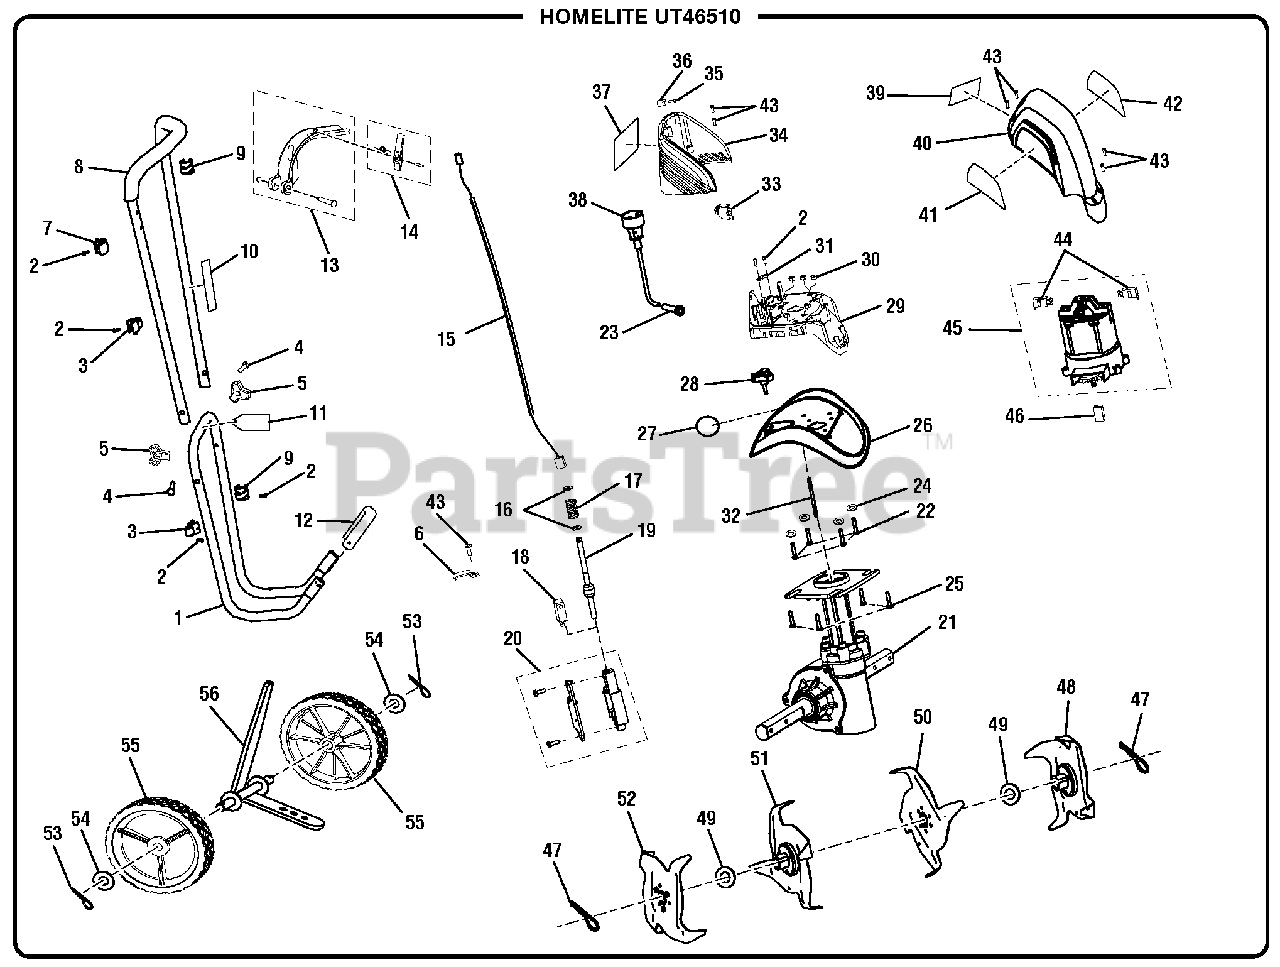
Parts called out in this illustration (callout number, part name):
1	Lower Handle
2	Screw (M4.2 x 14 mm)
3	Cable Retainer Ring
4	Handle Bolt
5	Handle Knob
6	Switch plate
7	Upper Cable Retainer Ring
8	Upper Handle Assembly
9	Cord Retainer Ring
10	Icon Warning Label
12	Front Handle Assembly
13	Switch Trigger Assembly
14	Switch Lock-out Assembly
15	Switch Cable Assembly
16	Retaining Ring
17	Compression Spring
19	Switch Actuator
20	Switch Box Assembly
21	Gear Box Assembly
22	Bolt (M6 x 35 mm Hex Hd.)
23	Bend Relief
24	Washer (M6)
25	Bolt (M6 x 25 mm, Hex Hd.)
26	Tine Shield Assembly
27	Foot Warning Label
28	Adjustment Knob
29	Motor Base
30	Lock Nut (M6)
31	Wire Clip
32	Flex Shaft
33	Circuit Breaker
34	Lower Motor Cover
35	Screw (M4 x12 mm)
36	Switch Cable Clip
37	Data Label
38	Power Cord
39	Warning Label
40	Upper Motor Cover
41	Logo Label (right)
42	Logo Label (left)
43	Screw (M4.2 x 18 mm)
44	Brush Assembly
45	Motor Assembly
46	Flex Shaft Adaptor
47	Hitch Pin
48	Tine Assembly (D)
49	Washer (Felt)
50	Tine Assembly (C)
51	Tine Assembly (B)
52	Tine Assembly (A)
53	Hitch Pin
55	Wheel Assembly (6 in.)
56	Axle/Drag Stake Assembly
